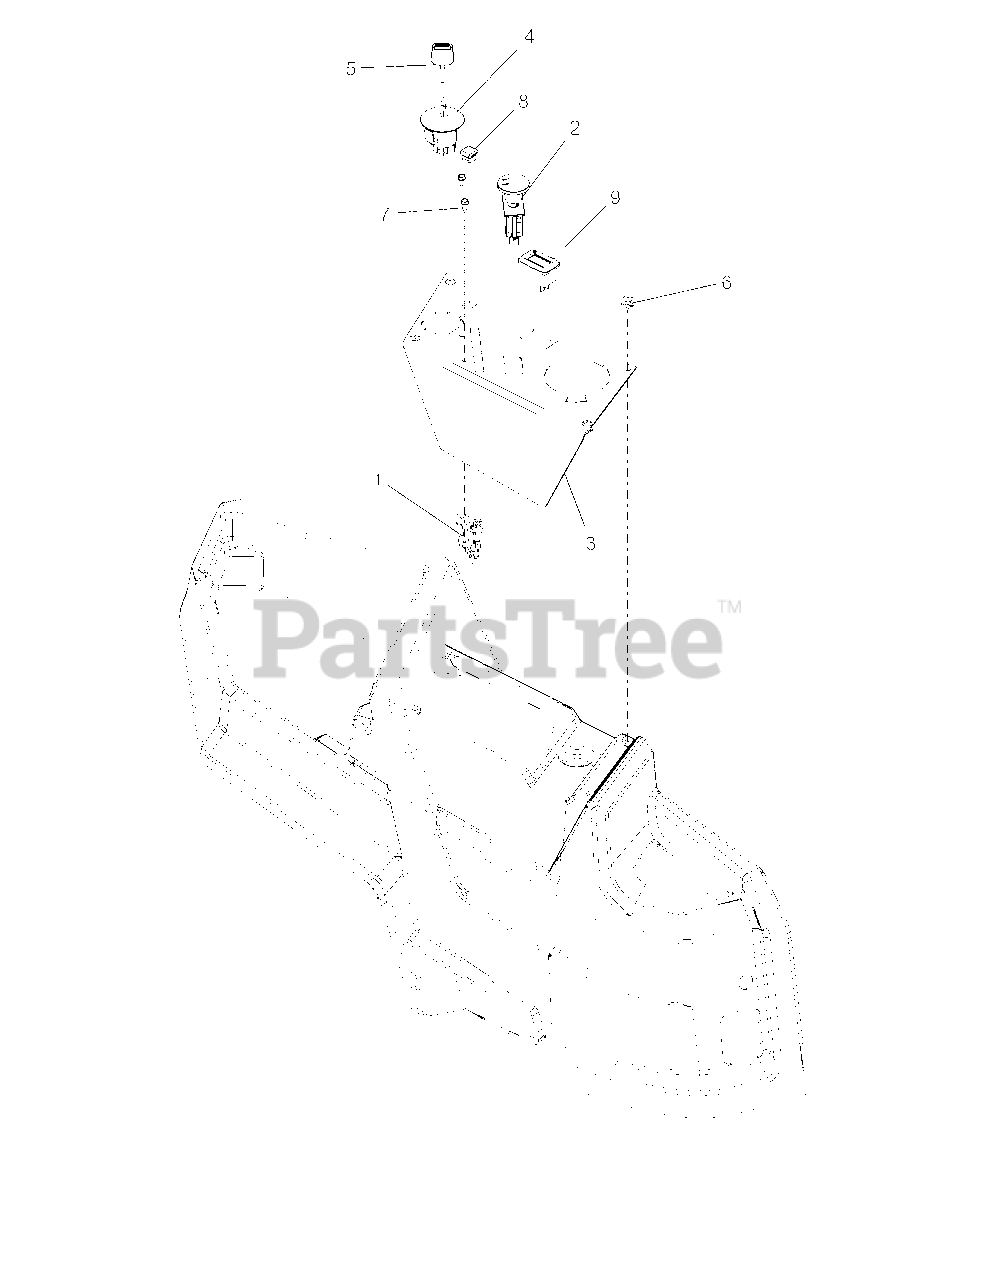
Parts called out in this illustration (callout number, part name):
1	CABLE - THROTTLE CONTROL
2	SWITCH, CLUTCH (YELLOW)
3	PANEL, CONTROL
4	KEYSWITCH-IGNITION 4 POS
5	KEY, IGNITION
6	RIVET, PLASTIC .195 DIA.
7	SCR,TAP #10-24X.50 HWH TR ZCC
8	PLUG, 5/8" SQ BLACK (14-20GA)
9	METER, HOUR W/MAINTENANCE
